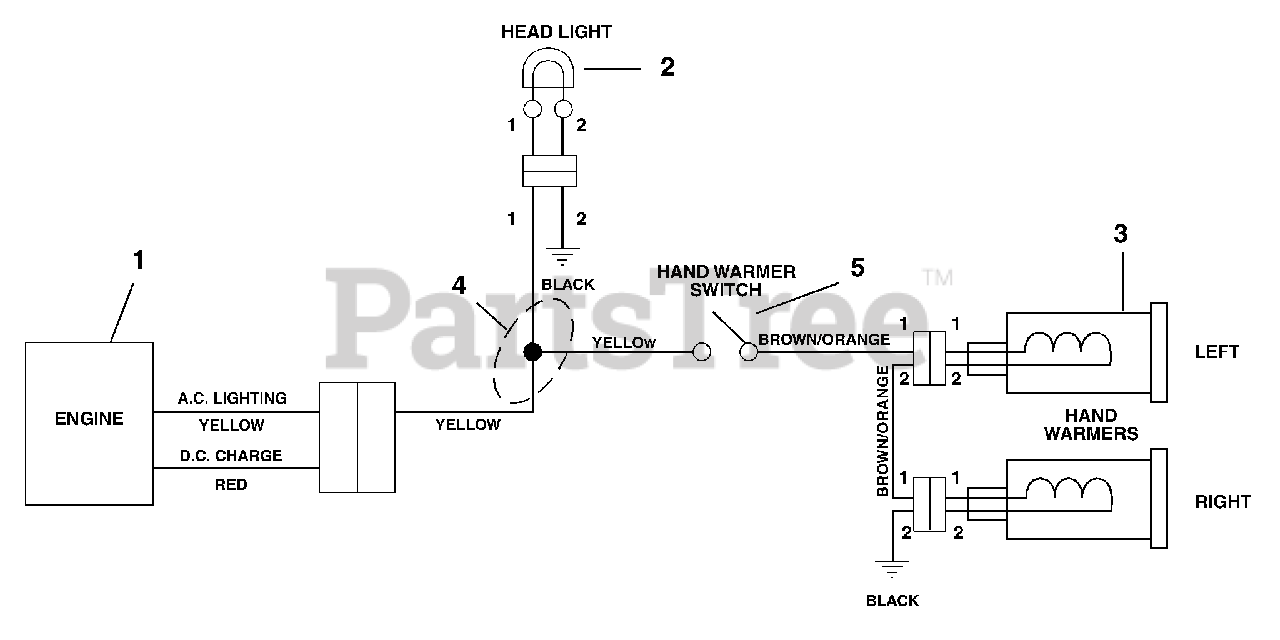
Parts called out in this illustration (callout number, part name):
1	ENGINE, 10HP LH TEC. - 120V
2	HEADLIGHT
3	WARMER, HAND W/TERMINAL
4	WIRE HARNESS-HOT GRIPS & LIGHT
5	SWITCH, ON/OFF
